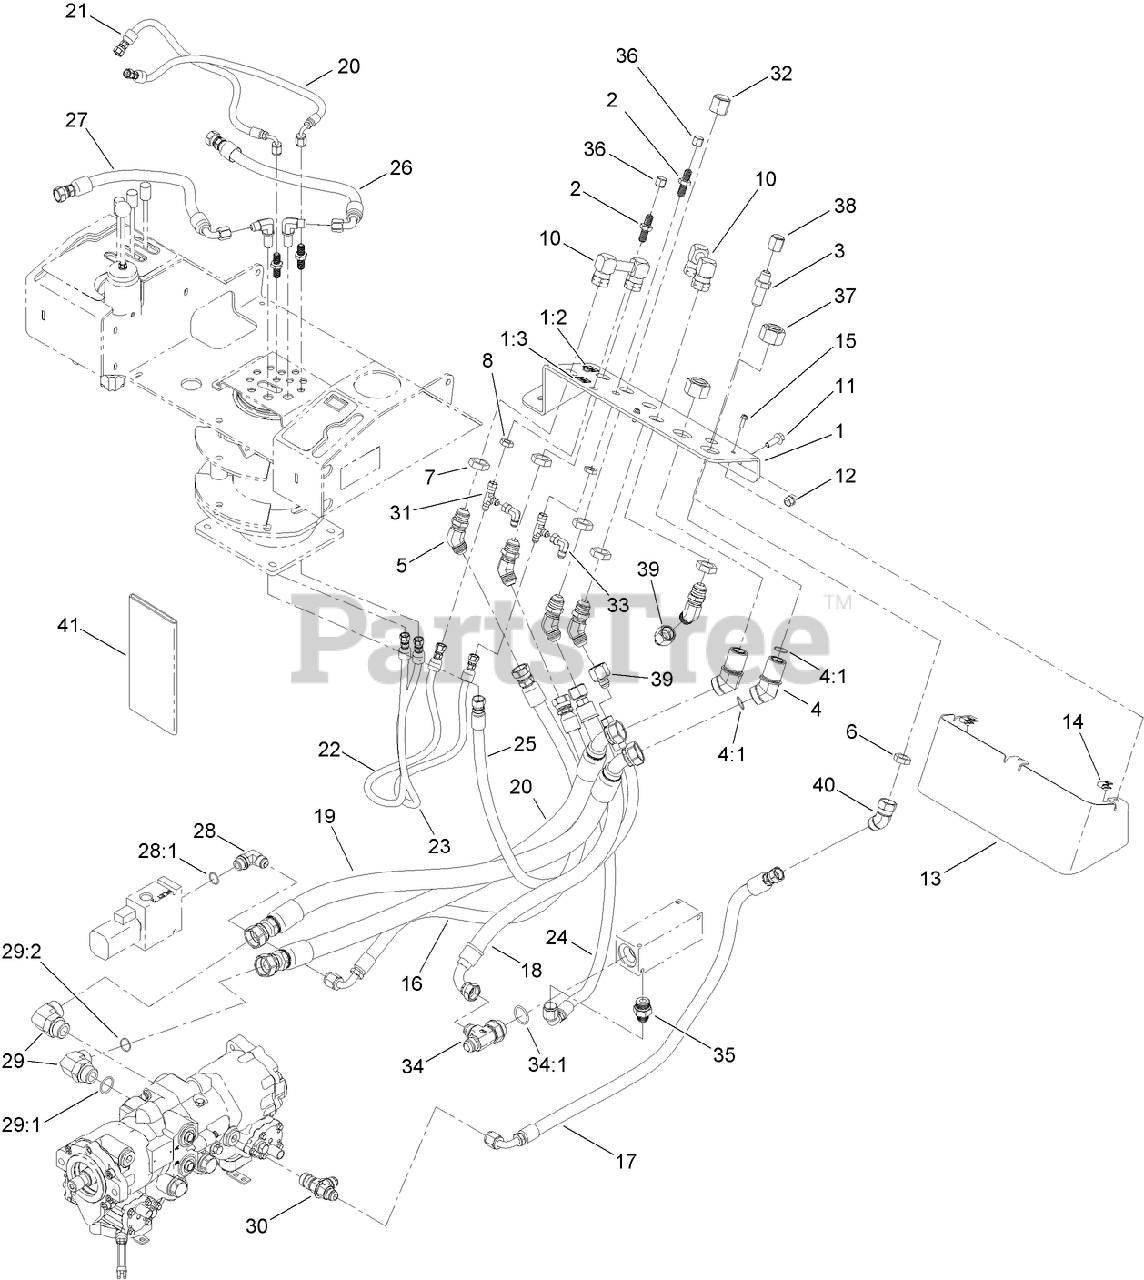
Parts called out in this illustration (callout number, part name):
1	BULKHEAD MOUNT PLATE ASM
1:2	DECAL-FLUID, HYDRAULIC (IN)
1:3	DECAL-FLUID, HYDRAULIC (OUT)
2	UNION-BULKHEAD
3	UNION-BULKHEAD
4	ELBOW-BULKHEAD, 45
4:1	O-RING
5	ELBOW-BULKHEAD, 45
6	NUT-LOCK, BULKHEAD
7	NUT-LOCK, BULKHEAD
8	NUT-LOCK, BULKHEAD
10	FITTING-SPECIAL
11	SCREW-HH
12	NUT-LOCK, NI
13	PLATE-COVER
15	SCREW-HHF
16	HOSE ASM
17	HOSE ASM
18	HOSE ASM
19	HOSE ASM
20	HOSE ASM
21	HOSE ASM
22	HOSE ASM
23	HOSE ASM
24	HOSE ASM
25	HOSE ASM
26	HOSE ASM
27	HOSE ASM
28	FITTING-ELBOW, 90 DEG
28:1	O-RING
29	FITTING-ELBOW, 90 DEG
29:1	O-RING
29:2	O-RING
30	FITTING-TEE
31	FITTING-HYD, TEE
33	ELBOW-SWIVEL, 90 DEG
34	FITTING-TEE
34:1	O-RING
35	FITTING-STRAIGHT
37	FITTING-CAP
38	FITTING-CAP
39	FITTING-STRAIGHT
40	FITTING-ELBOW, 45 DEG
41	SLEEVE-PROTECTIVE
